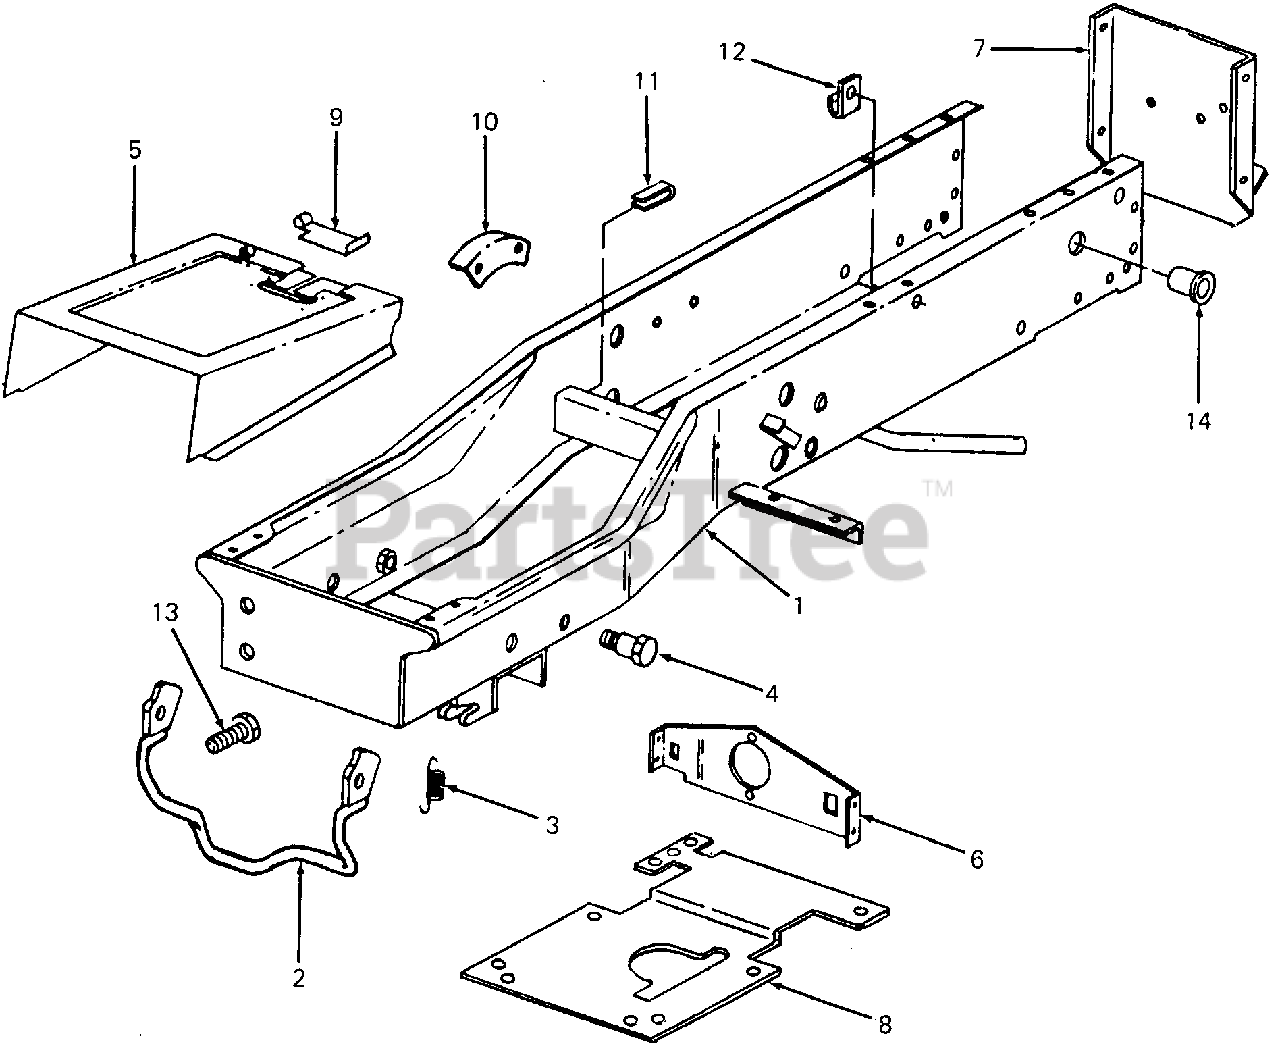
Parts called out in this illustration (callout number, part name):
2	Latch Assembly, Quick
3	Spring, Latch
4	Bolt, Shoulder
5	Cover, Frame w/Graphic
6	Bracket, Angle Drive
9	Stop, 2nd Gear
10	Bracket, Height Indicator
11	Clip, Steering Bracket Cable
12	Clip, Cable
13	Screw, Adjustment, 1/2-20 X 1.0 Lg GR5
14	Bushing, Snap
